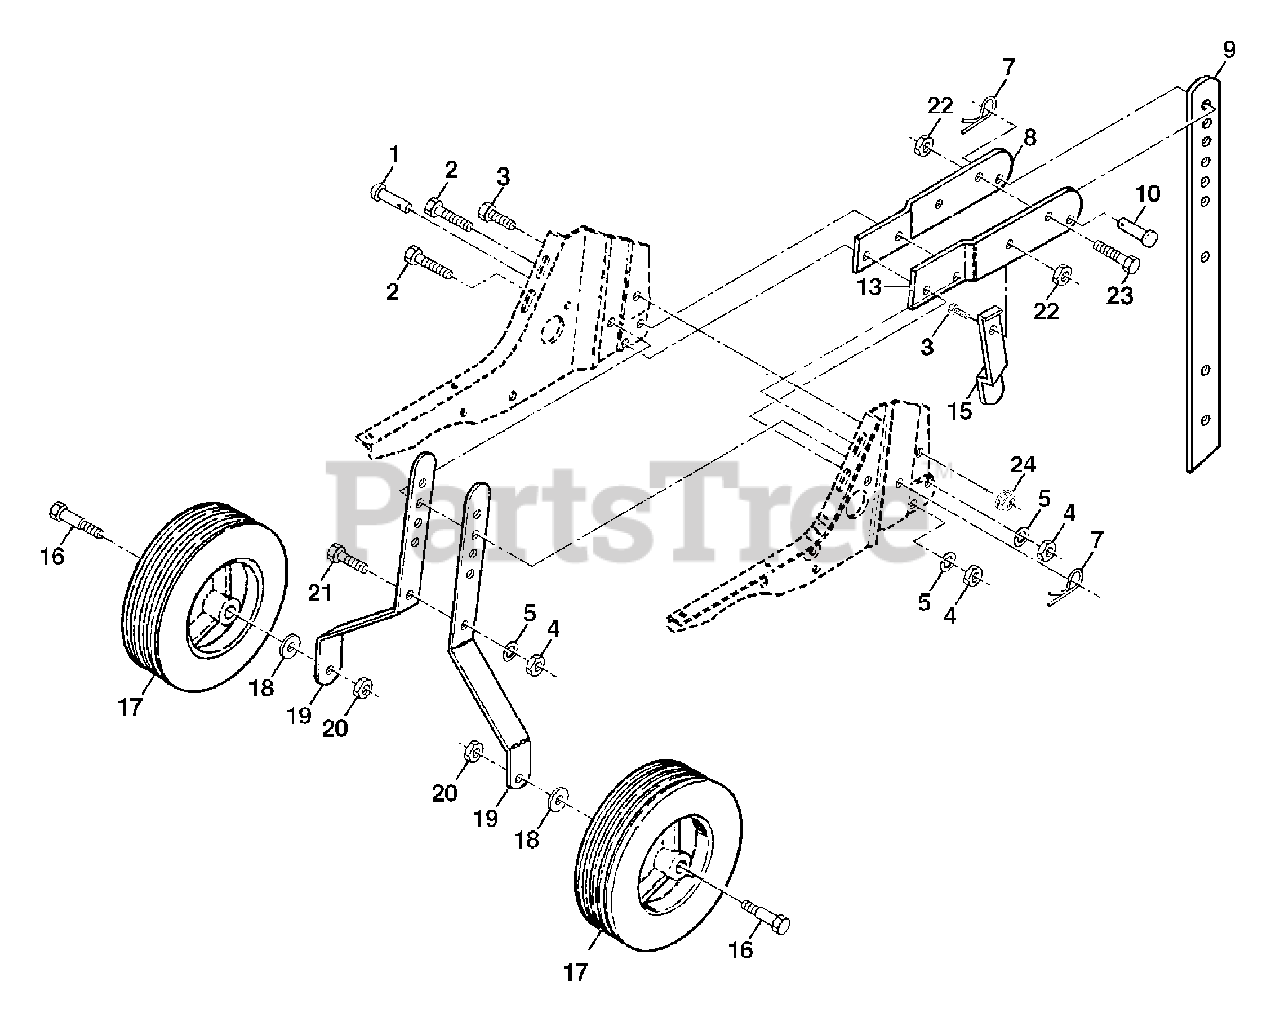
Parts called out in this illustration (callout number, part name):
1	Pin, Clevis
2	Bolt, Hex 5/16-18 x 1-1/4
3	Bolt, Hex 5/16-18 x 3/4
4	Nut, Hex 5/16-18
5	Washer, Lock 5/16
6	Locknut, w/washer 3/8-16
7	Clip, Hairpin
8	Support, Depth Stake, R.H.
9	Stake, Depth
10	Pin, Clevis
11	Bolt, Hex, Fin 3/8-16 x 1-3/4
13	Support, Depth Stake, L.H.
15	Spring, Stake
16	Bolt, Shoulder
17	Wheel
18	Washer 13/32 x 13/16 x 11 Ga.
19	Bracket, Wheel
20	Locknut, Crown 3/8-16
21	Bolt, Hex 5/16-18 x 1
22	Locknut, w/insert 5/16-18
24	Nut Lock Hex Flange
